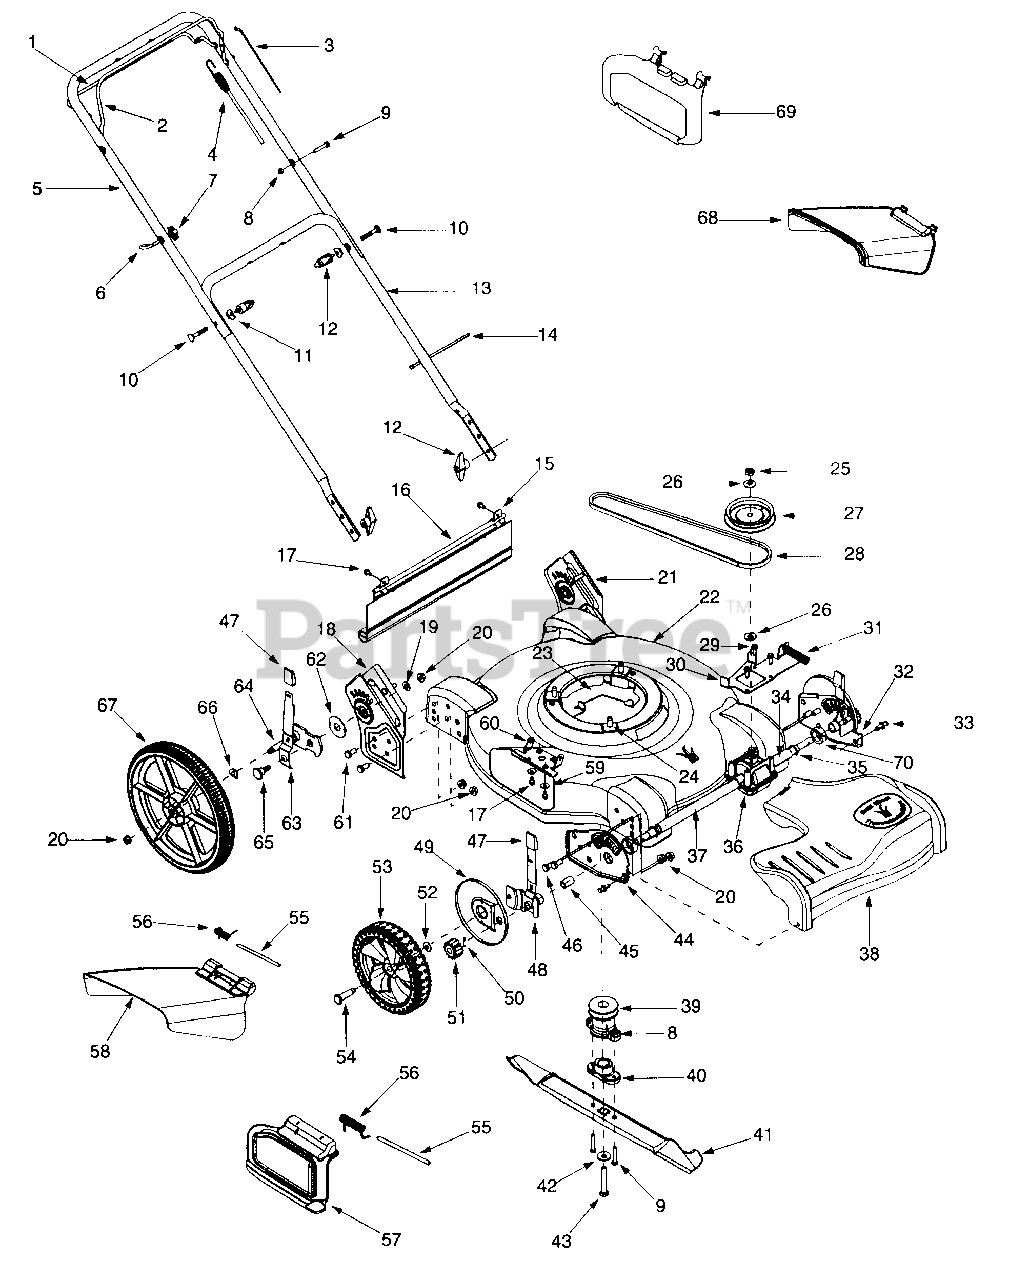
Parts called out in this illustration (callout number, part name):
1	Drive Control Handle
2	Blade Control Handle
3	Blade Control Cable - B&S
3	Blade Control Cable- Tec
4	Drive Control Cable 5/16 dia. shank ball end
4	Drive Control Cable Z fitting end, die cast
6	Eye Bolt
7	Wing Nut 1/4-20
8	Hex Lock Nut 1/4-20
9	Hex Cap Screw 1/4-20 x 1.5
10	Carriage Bolt 5/16-18 x 2.0
11	Shoulder Washer .320 ID x .93 OD
12	Wing Nut
14	Cable Tie
15	Hinge Clip
16	Trail Shield
17	Hex Screw 1/4-14 x .625
19	Flat Washer .406 ID x .812 OD
20	Lock Nut 3/8-16
23	Engine Belt Keeper Bracket
24	Hex Washer Screw 3/8-16 x 1.875
25	Jam Nut 7/16-20
26	Bell Washer .45 ID x 1.00 OD
27	Pulley
28	V-Belt
29	Hex Washer Screw 1/4-20 x .750
30	Transmission Belt Keeper Bracket
31	Compression Spring
33	Rivot
34	Sleeve Spacer .550 ID x 2.5
35	Retainer Ring
36	Transmission Assembly
37	Sleeve Spacer .550 ID x 8.9
38	Transmission Cover
39	Drive Pulley
40	Blade Adapter
41	Blade 22"
41	Mulching Blade 22"
42	Bell Washer .396 ID x 1.140 OD
43	Hex Cap Screw 3/8-24 x 2.5
45	Sleeve Bearing
46	Hex Cap Screw 3/8-16 x .75
47	Adjustment Knob
48	Spring Lever Assemby
49	Wheel Dust Cover
50	Pin
51	Spur Gear 14T - LH
51	Spur Gear 14T - RH
52	Bell Washer .401 ID x .870 OD
53	Wheel Assembly 8 x 1.8
54	Shoulder Screw 3/8-16
55	Hinge Pin
56	Torsion Spring - Side Discharge
56	Torsion Spring - Mulching Baffle
57	Mulching Baffle (If Equipped)
58	Side Discharge Assembly
59	Bell Washer .265 ID x .75 OD
60	Chute Hinge
61	Hex Cap Screw 3/8-16 x .75
62	Thrust Bearing .688 ID x 1.938 OD
63	Spring Lever
64	Rear Pivot Arm Assembly
65	Shoulder Screw 3/8-16
66	Spring Washer
67	Wheel Comp 14 x 1.8
68	Snap Discharge Chute
69	Snap Mulching Plug
70	Bearing Spacer
